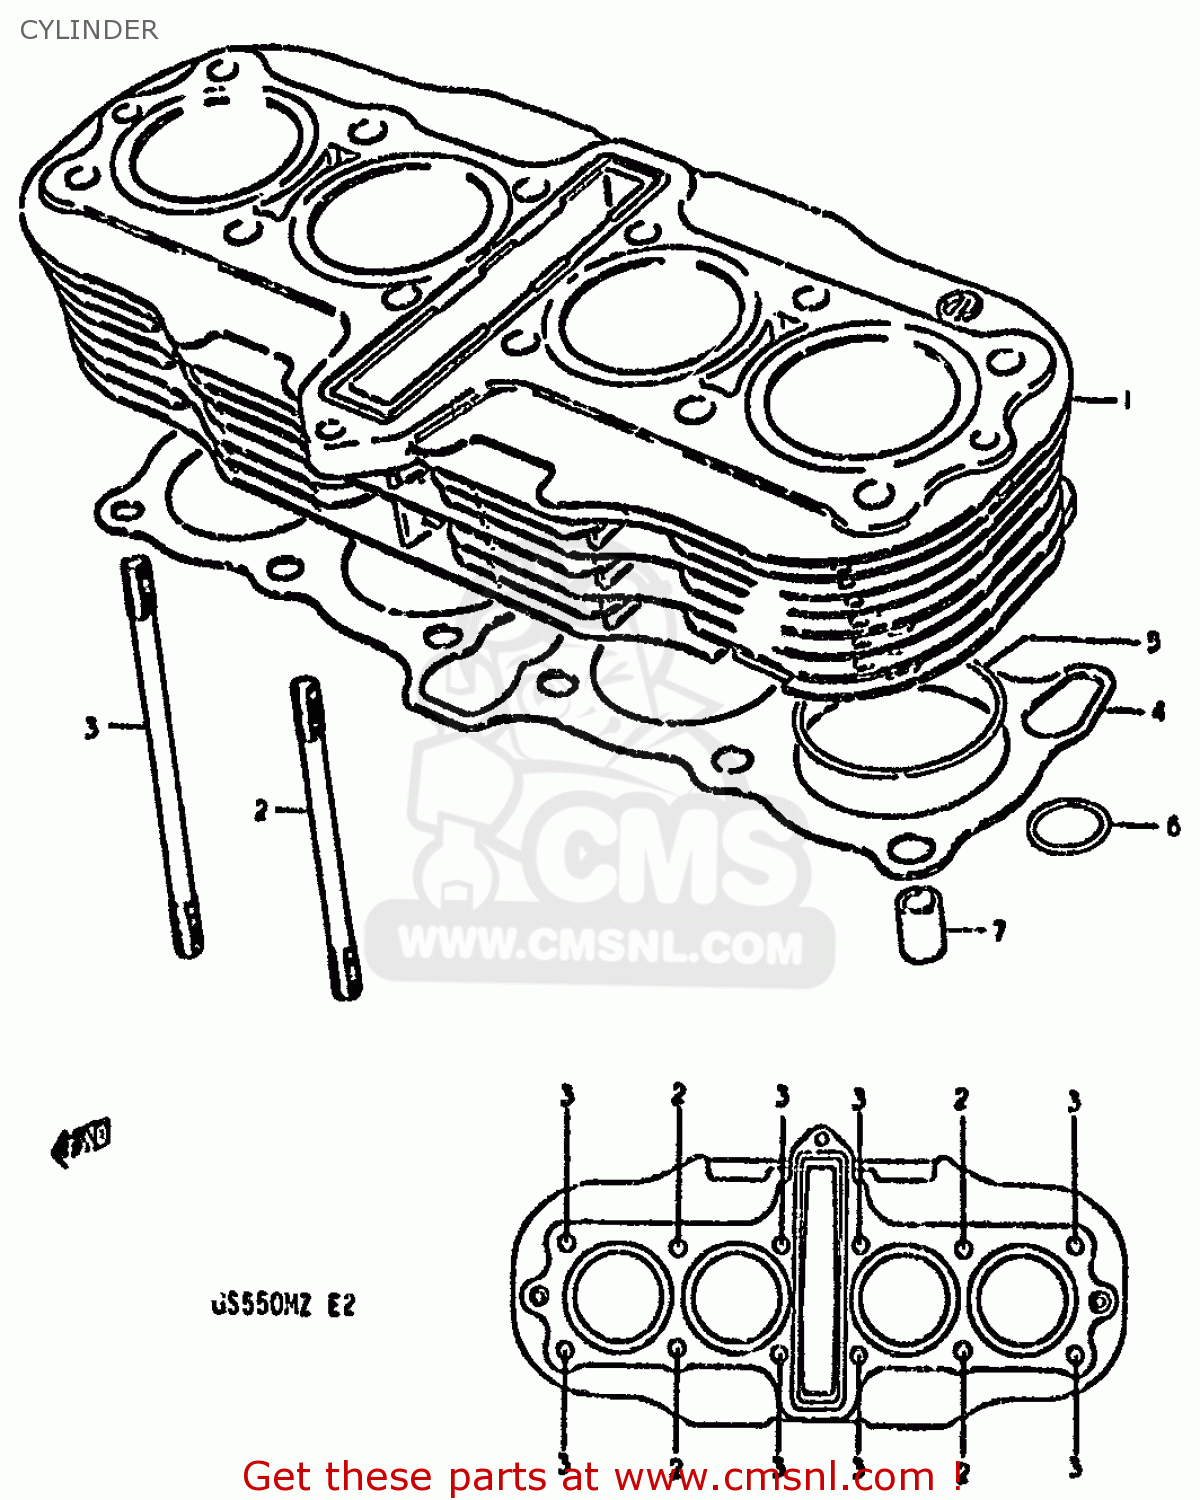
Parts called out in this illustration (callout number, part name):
1	CYLINDER
2	BOLT,STUD
3	BOLT,STUD
4	GASKET,CYLINDER (MCA)
5	O RING(D:2,ID:61)
6	INVALID PARTNUMBER
7	PIN
